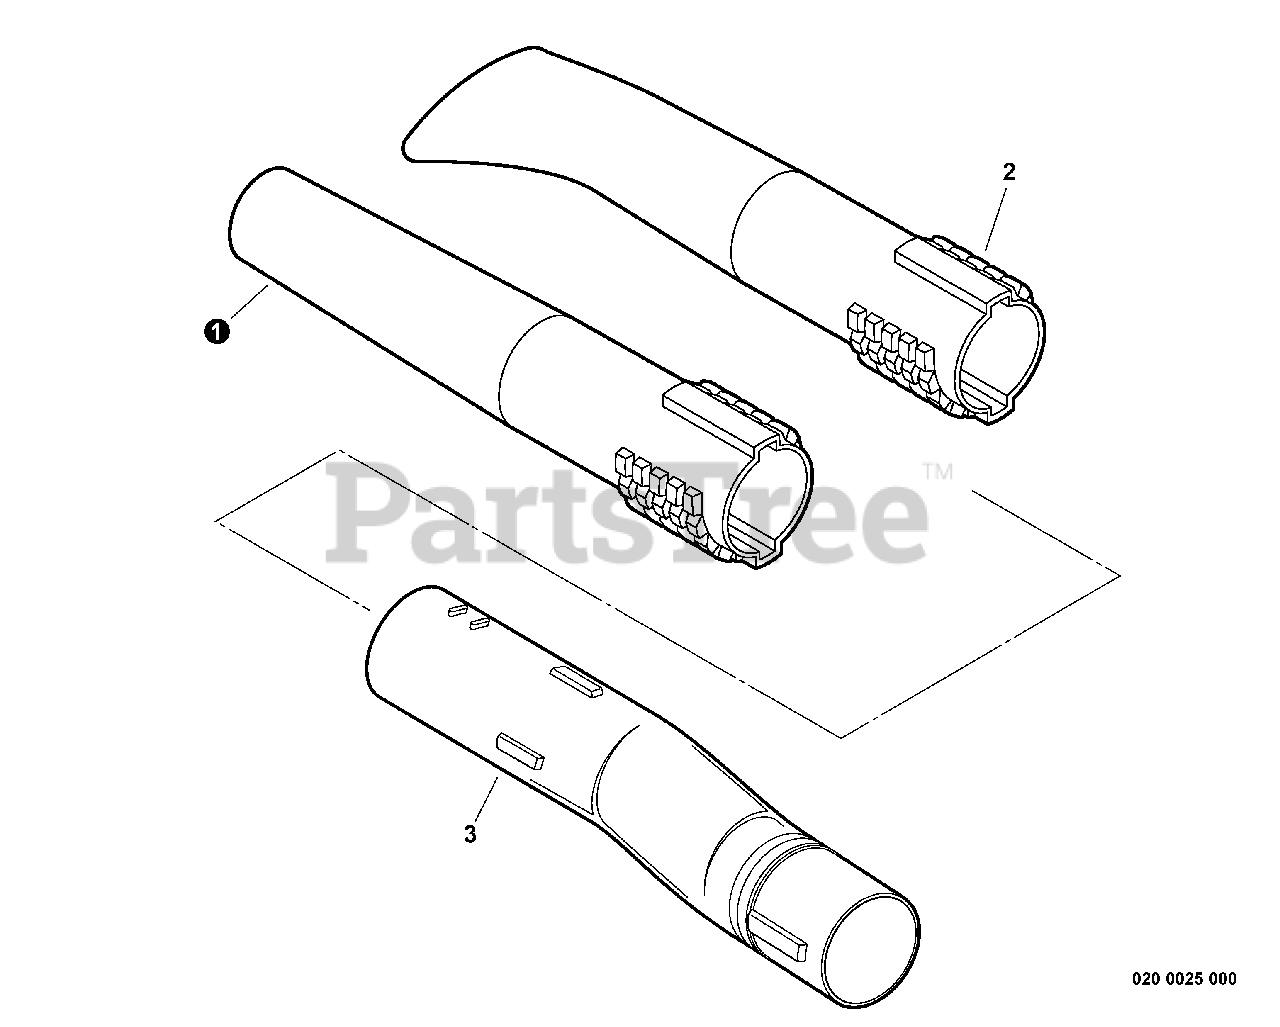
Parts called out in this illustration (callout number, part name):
1	TUBE, BLOWER - STRAIGHT NOZZLE
2	TUBE, BLOWER - CURVED NOZZLE
3	TUBE, BLOWER - CURVED
